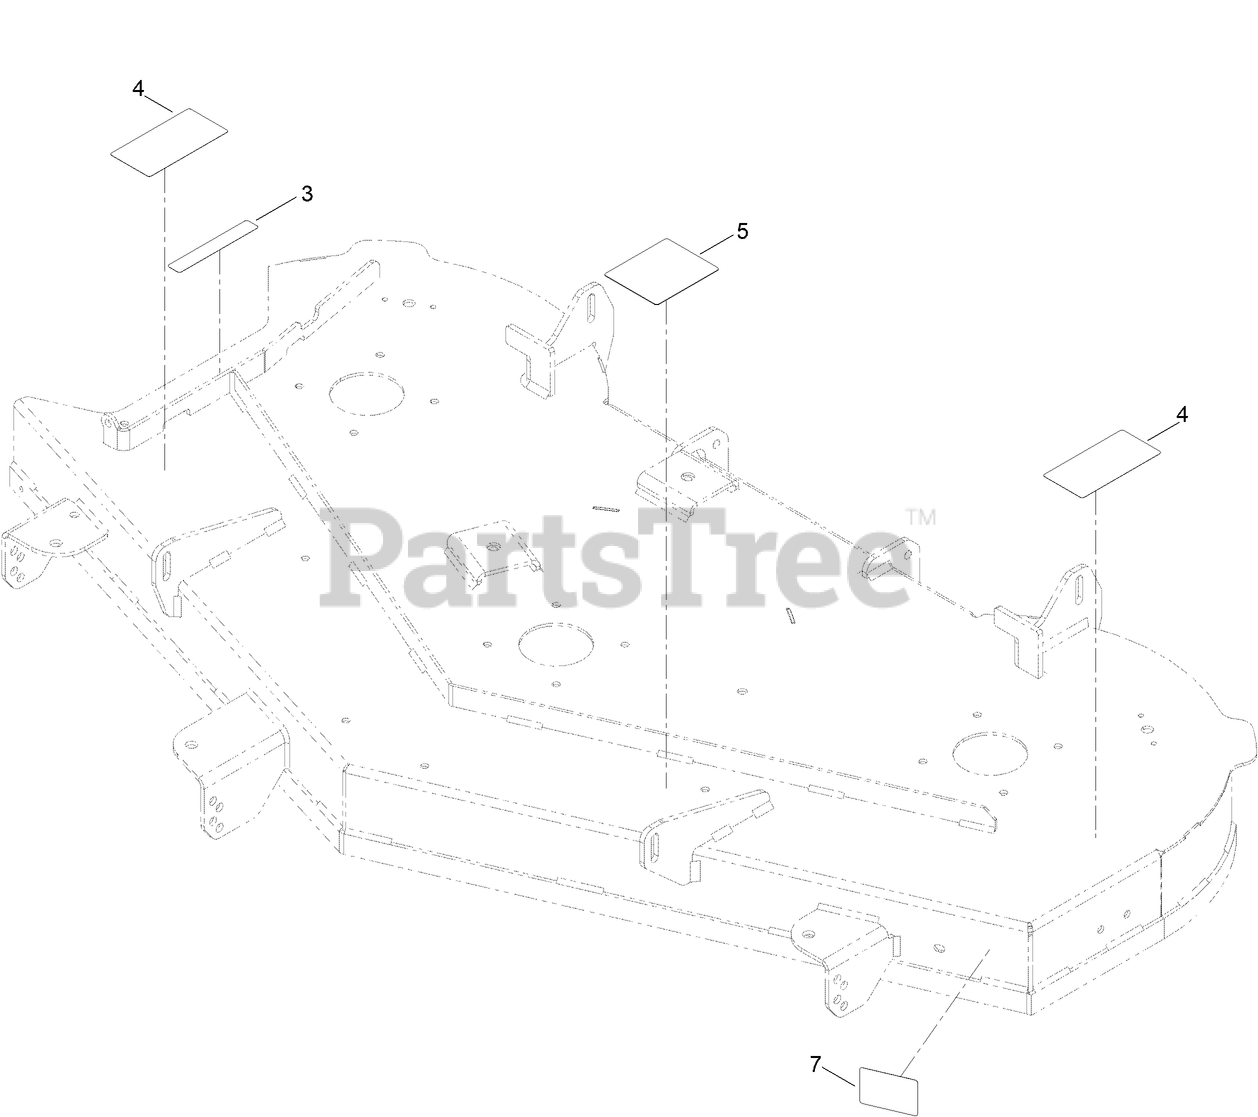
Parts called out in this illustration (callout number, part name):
3	DECAL-DANGER
4	DECAL-DANGER, DECK
5	DECAL-ROUTING, BELT
7	DECAL-SCALP, ANTI
